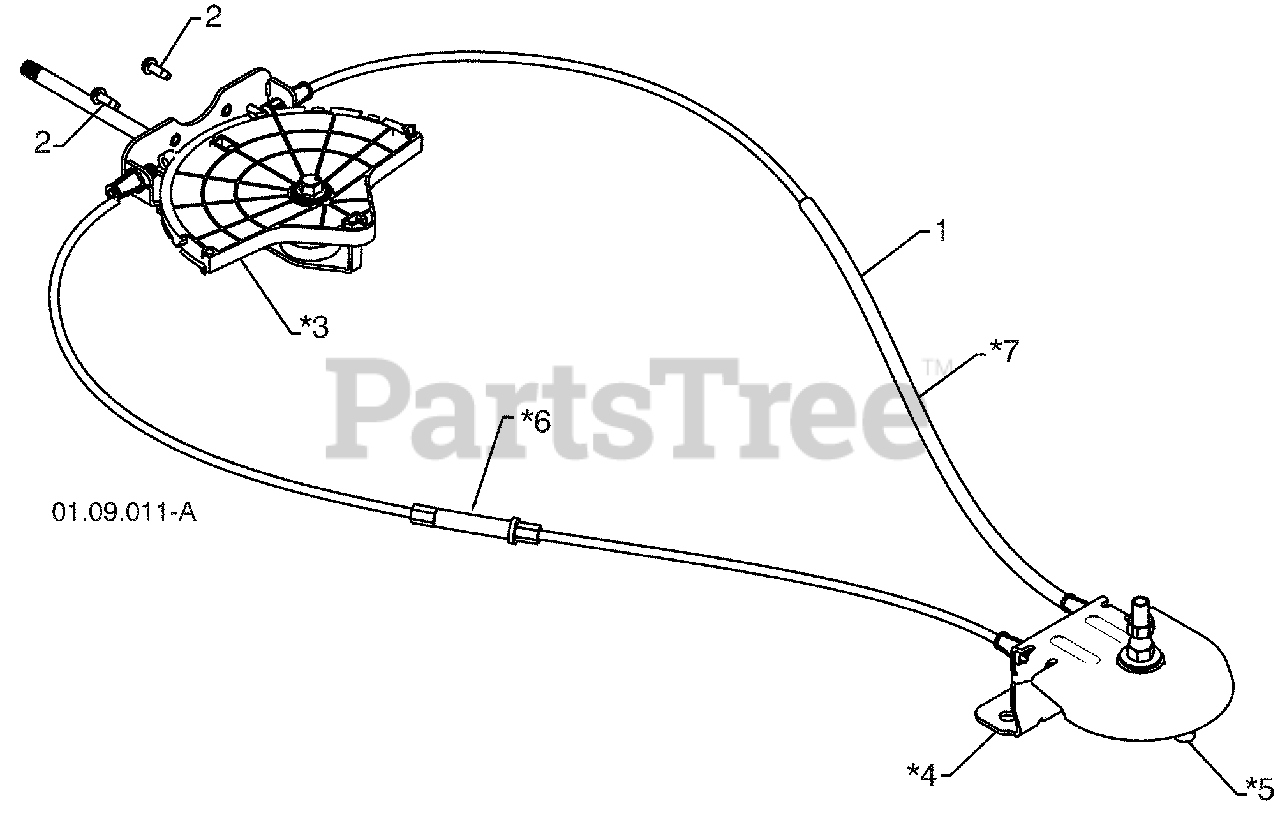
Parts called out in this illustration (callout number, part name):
1	LEVER/CABLE ROTATOR ASSEMBLY
2	SCREW 10-24 X .625
3	ROTATOR HEAD
4	ROTATOR PIVOT BRACKET
5	PULLEY PIVOT
6	CABLE ASSEMBLY ADJUSTABLE GRAY
7	CABLE ASSEMBLY HEAT SHIELD GRAY
